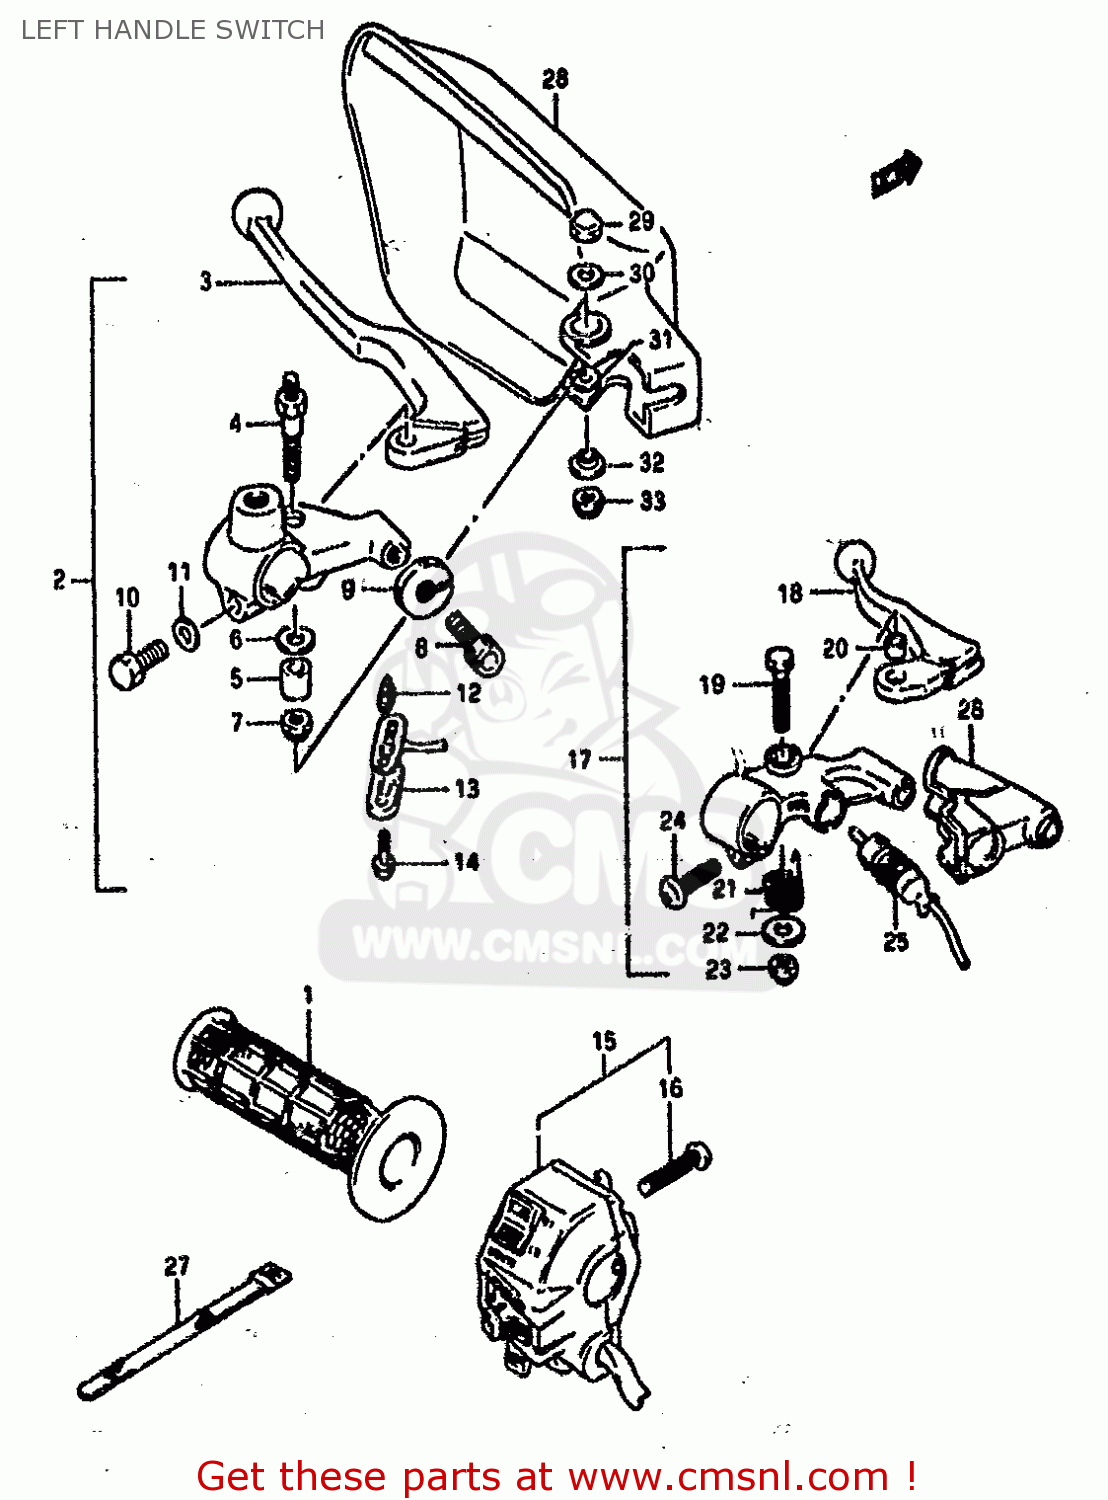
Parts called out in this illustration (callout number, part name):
1	GRIP,L
2	LEVER ASSY,CLUTCH
3	LEVER,CLUTCH
4	BOLT,LEVER SET
5	SPACER,LEVER SET
6	WASHER,LEVER SET
7	NUT
8	ADJUSTER,CABLE
9	NUT,LOCK
10	BOLT
11	WASHER
12	CONTACT,SWITCH
13	COVER,FR BK TERMINAL BASE
14	SCREW
15	SWITCH ASSY,HANDLE LH
16	SCREW
17	LEVER ASSY,DECOMP
18	LEVER
19	BOLT
20	SPACER
21	SPRING
22	WASHER
23	NUT
24	SCREW
25	SWITCH
26	COVER,DECOMP,DUST
27	CLAMP(L:120)
28	COVER,KNUCKLE,L
29	NUT 6MM
30	WASHER (6.5X20X1.6)
31	WASHER(6.5X16X1.2)
32	WASHER
33	NUT
